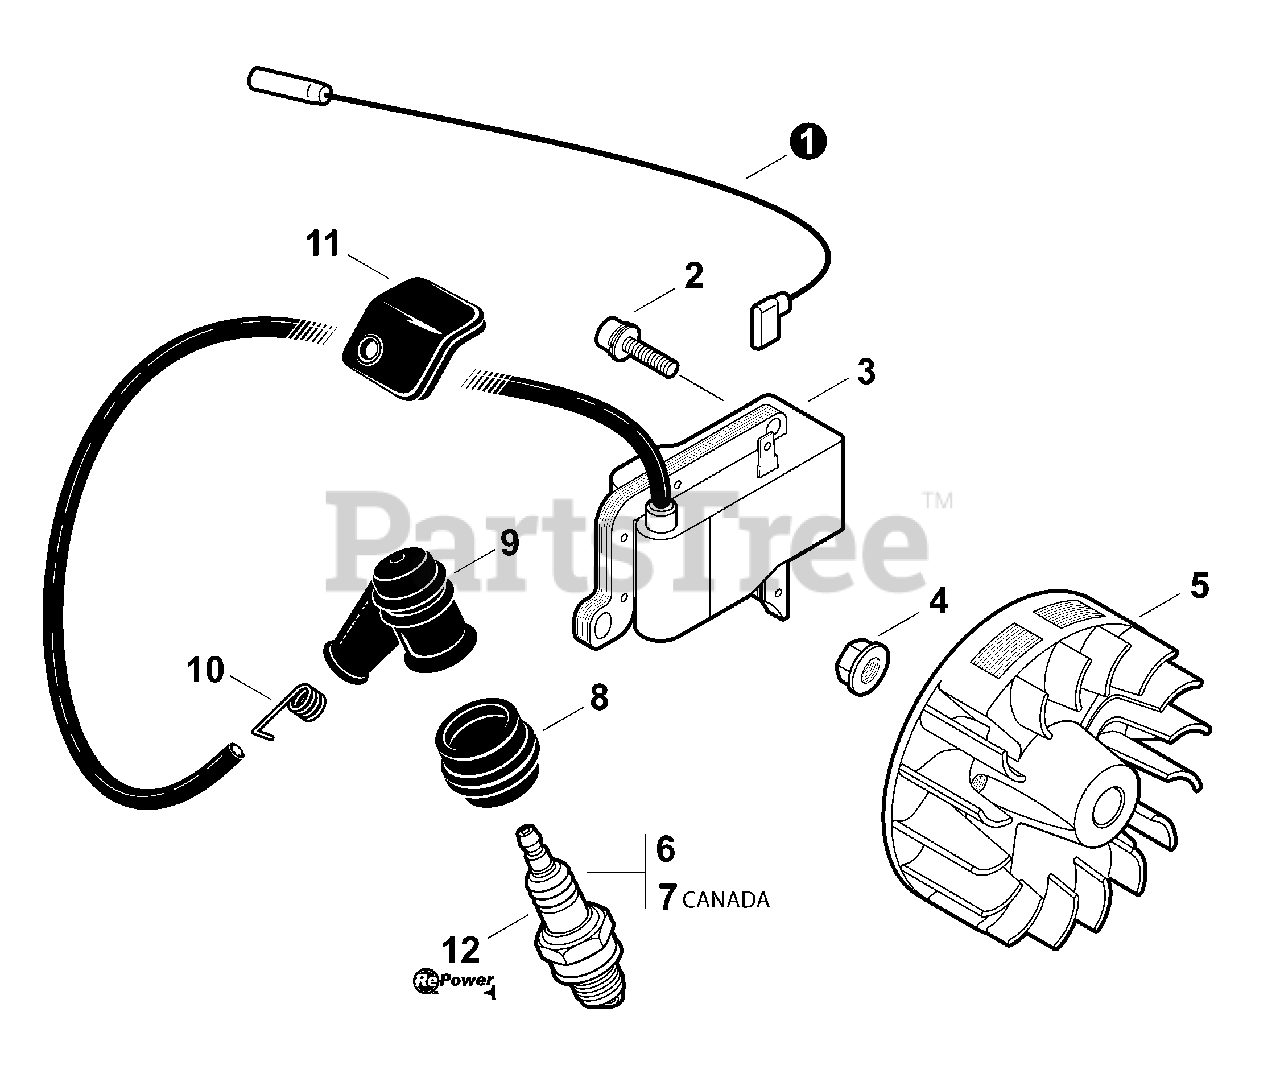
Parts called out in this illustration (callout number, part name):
1	LEAD, IGNITION
2	SCREW - 5×16
3	COIL, IGNITION
4	NUT - 8 -- FLANGE
5	FLYWHEEL
6	SPARK PLUG -- BPM8Y
7	SPARK PLUG -- BPMR8Y
8	COVER, SPARK PLUG CAP
9	CAP, SPARK PLUG
10	TERMINAL, SPARK PLUG CAP
11	COVER, IGNITION
12	RePower TUNE-UP KIT
